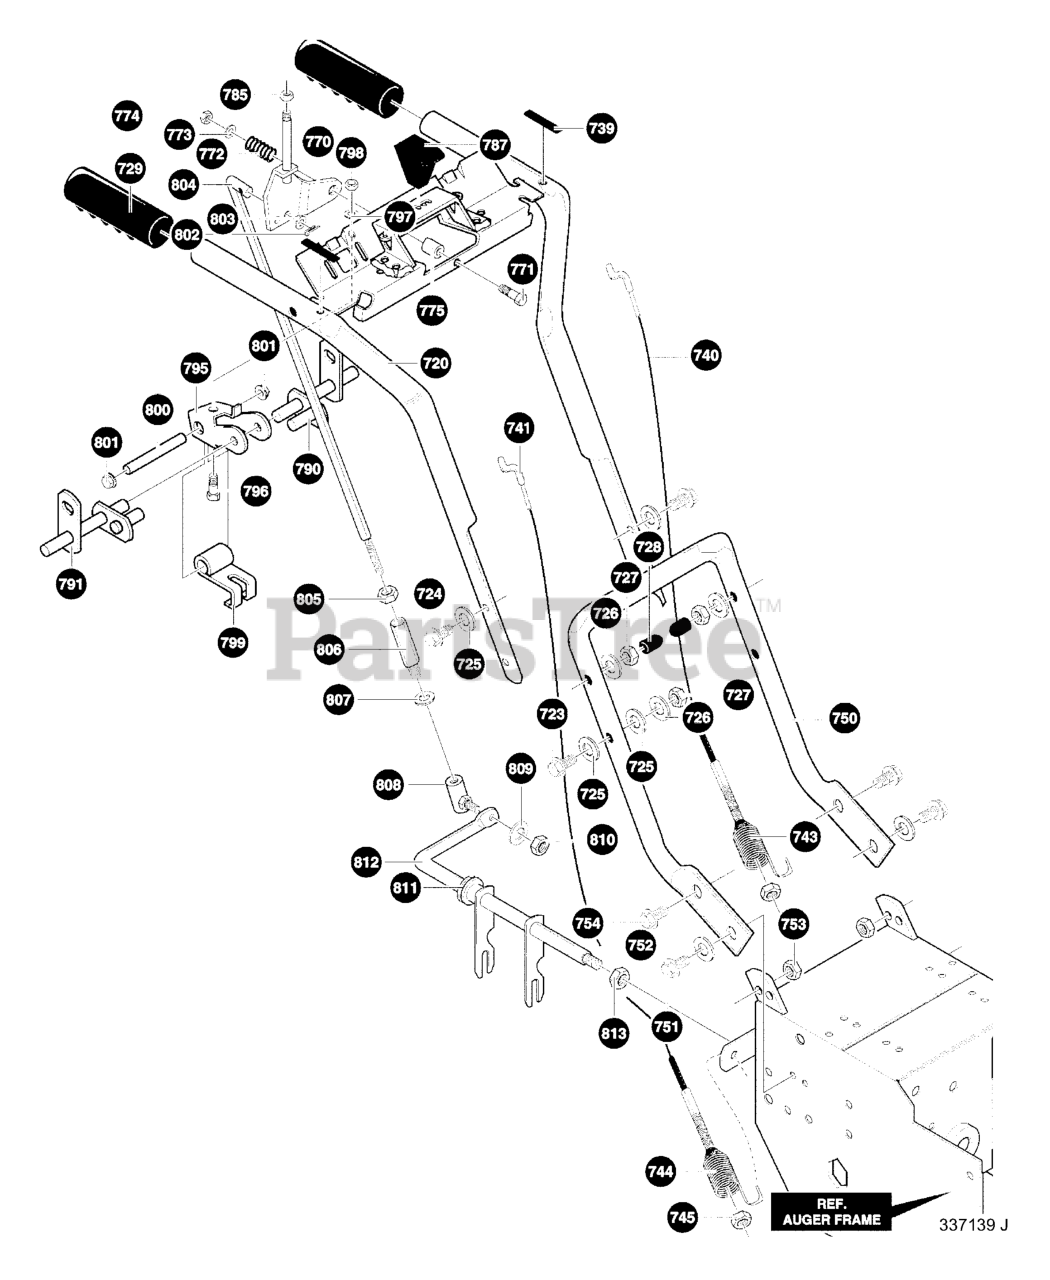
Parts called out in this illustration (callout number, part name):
720	ASSEMBLY, HANDLE
723	SCREW, 3/8-16 x 2.00
724	SCREW, 3/8-16 x 3.00
725	WASHER, FLAT
726	WASHER
727	NUT, 3/8-16
728	STOP, PLASTIC
729	GRIP, HANDLE
739	BUMPER, RECT
740	CABLE, CLUTCH 32.19"
741	CABLE, AUG CLUTCH
743	TENSION SPRING
744	SPRING, AUGER CLUTCH
745	NUT, 1/4-20 HEX NYLOCK
750	HANDLE, LOWER
751	SCREW, 5/16-18 x 0.75
752	WASHER, SPTLK
753	NUT, 5/16-18
754	SCREW, 5/16-18 x 0.75
770	BRKT, SHIFT ACTUATOR
771	SCREW, 3/8-16 x 3.00
773	WASHER, FLAT
774	NUT, 3/8-16 HEXNYL
775	SPACER, SHIFT ACTUATOR
785	NUT, 1/4-20
787	KNOB, SHIFT 1/420
790	ROD, ASSY LH
791	ROD, ASSY RH
795	BRACKET, CAM RETAINER
796	SCREW, 5/16-18 x 0.75
797	WASHER
798	NUT, 5/16-18
799	CAM LOCK
800	PIN, SPRING PIVOT
801	NUT, PUSH ON
802	PIN, COTTER
803	FLATWASHER
804	ROD, SPEED CONTROL
805	NUT, 5/16-24
806	ADAPTOR, ROD SPEED
807	WASHER
808	JOINT, STEEL BALL
809	WASHER
810	NUT, 5/16-24
811	BEARING, FL
812	ROD, ASSY YOKE "PANEL"
813	NUT, 38-16
